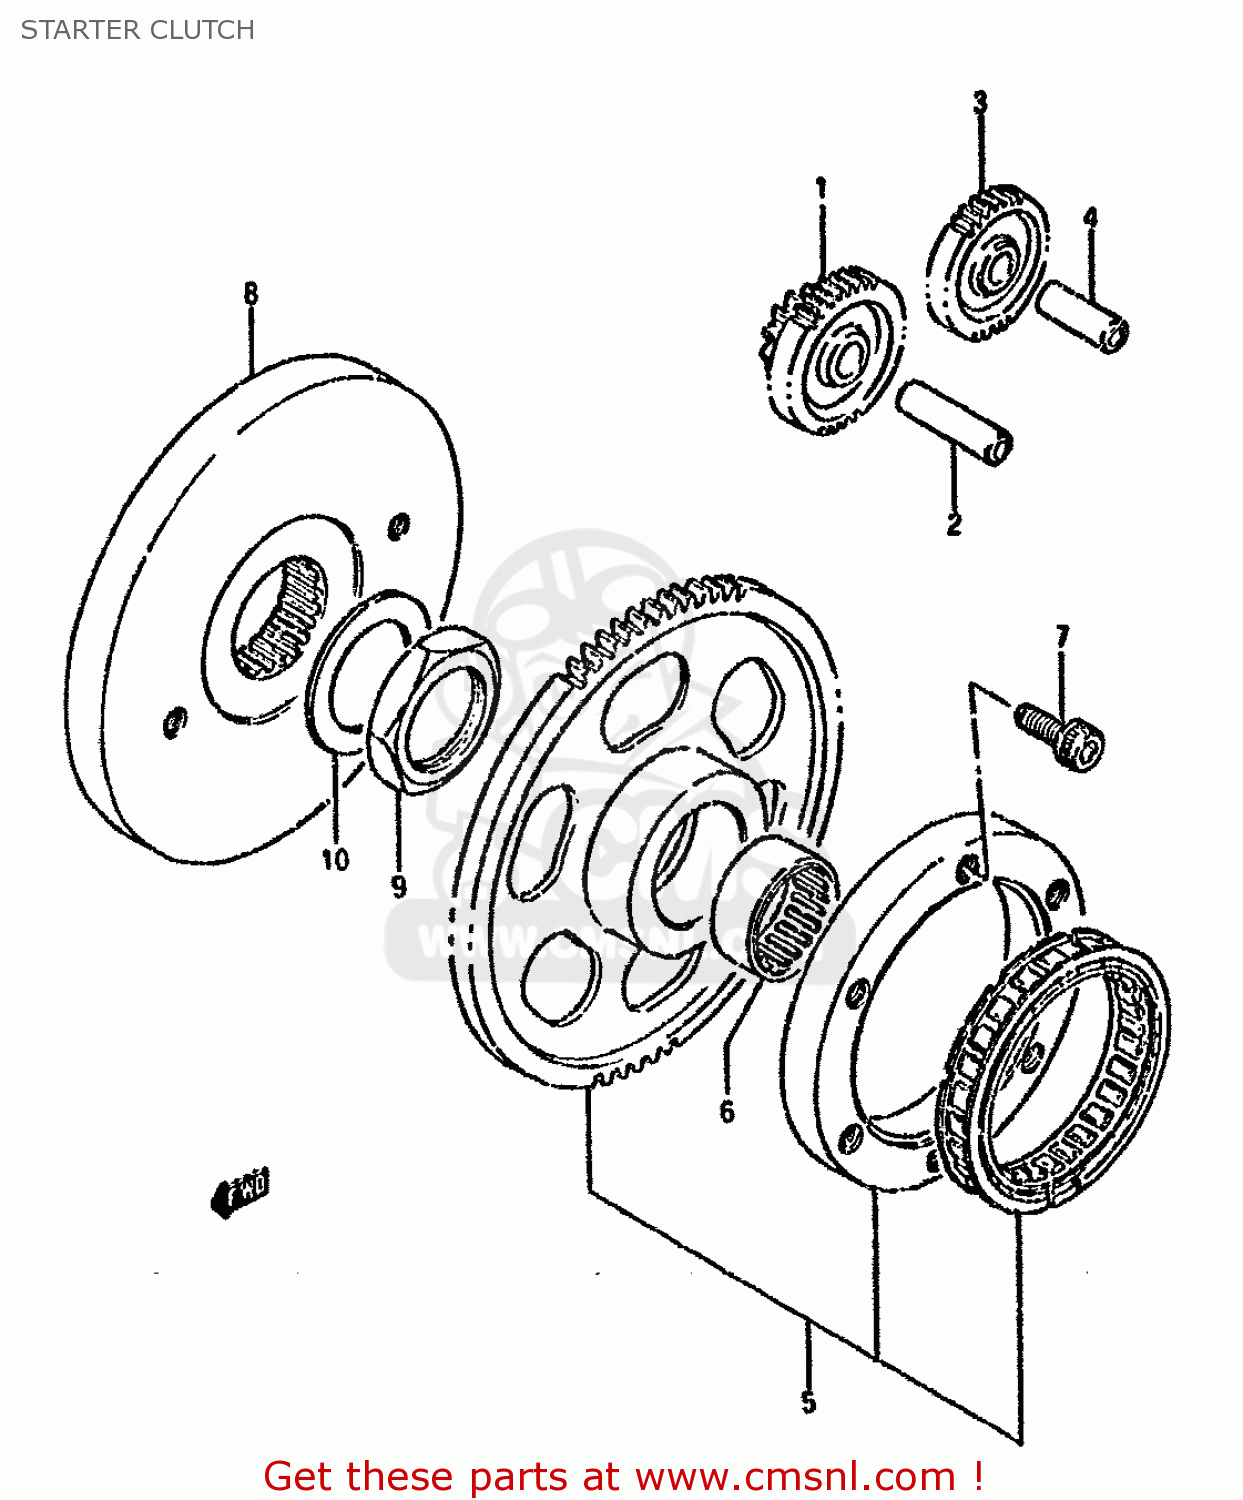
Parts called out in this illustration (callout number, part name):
1	GEAR,STARTER IDLE
2	PIN
3	GEAR,STARTER IDLE
4	PIN
5	CLUTCH SET,STARTER
6	BEARING(31X39X17.8)
7	BOLT
8	FLYWHEEL
9	NUT,FLYWHEEL
10	WASHER
